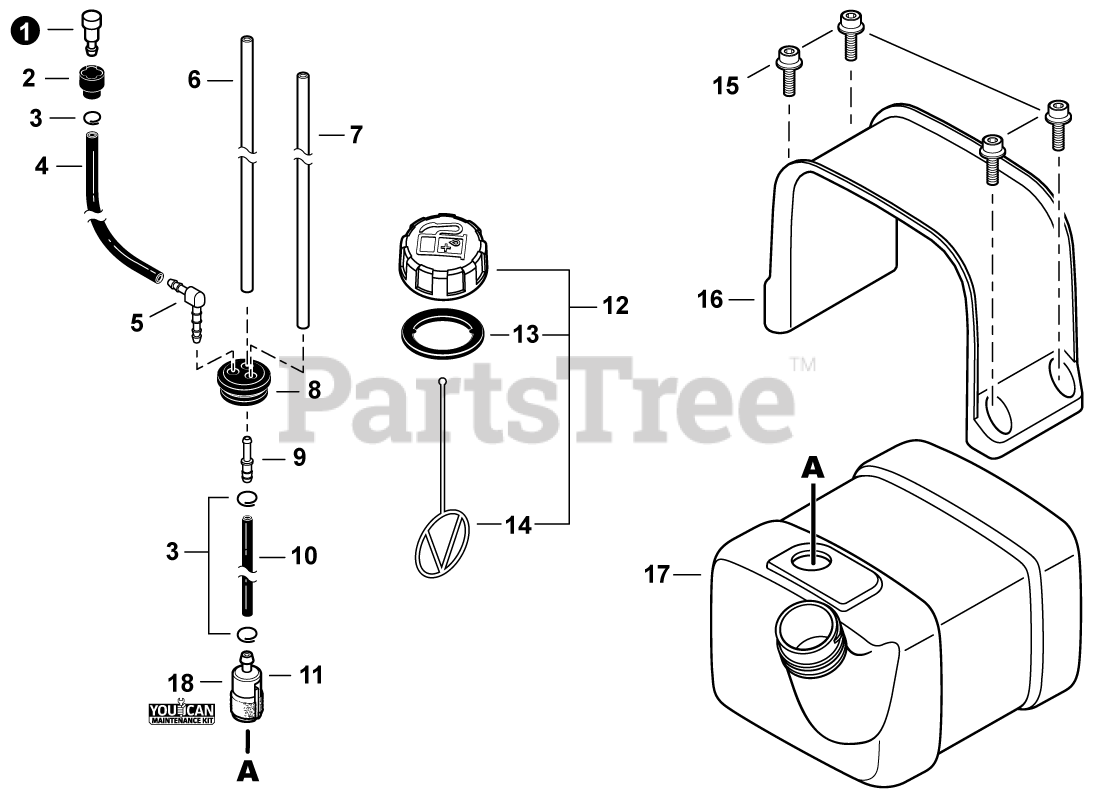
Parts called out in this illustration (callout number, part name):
1	VENT ASSY
2	HOLDER, VENT
3	CLIP 6.5 MM
4	PIPE, VENT 3x6x145 BLACK
5	CONNECTOR, PIPE
6	PIPE, FUEL 3.5x6x110 CLEAR
7	PIPE, FUEL RETURN 3x6x145 YELLOW
8	GROMMET, FUEL
9	CONNECTOR, PIPE 5x3.5
10	PIPE, FUEL 3x6x120 BLACK
11	FILTER, FUEL
12	CAP ASSY, FUEL
13	GASKET, FUEL CAP
14	CONNECTOR, CAP L= 100 MM
15	BOLT 5x16
16	BRACKET, FUEL TANK
17	TANK, FUEL
18	TUNE-UP KIT - YOUCANT
